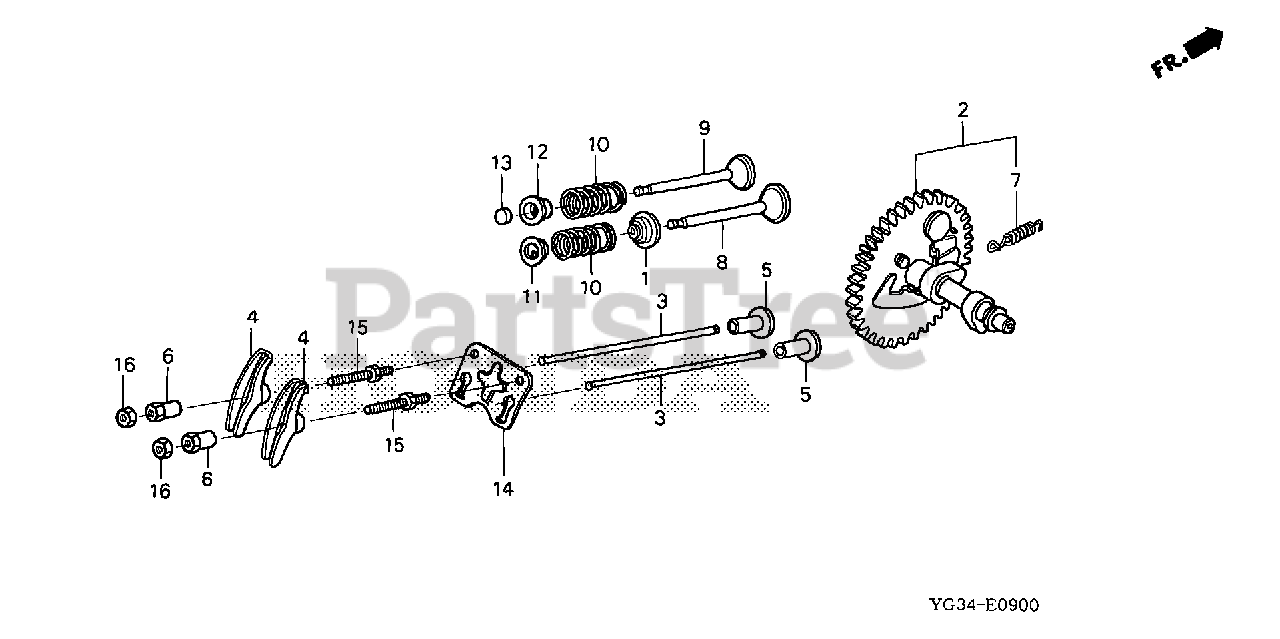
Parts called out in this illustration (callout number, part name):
1	SEAL, VALVE STEM
2	CAMSHAFT ASSY.
4	ARM, VALVE ROCKER
5	LIFTER, VALVE
6	PIVOT, ROCKER ARM
7	SPRING, WEIGHT RETURN
8	VALVE, IN.
9	VALVE, EX.
10	SPRING, VALVE
11	RETAINER, VALVE SPRING (EXHAUST SIDE)
12	RETAINER, VALVE SPRING (EXHAUST SIDE)
14	GUIDE, PUSH ROD
15	BOLT, PIVOT (8MM)
16	NUT, PIVOT ADJ.
